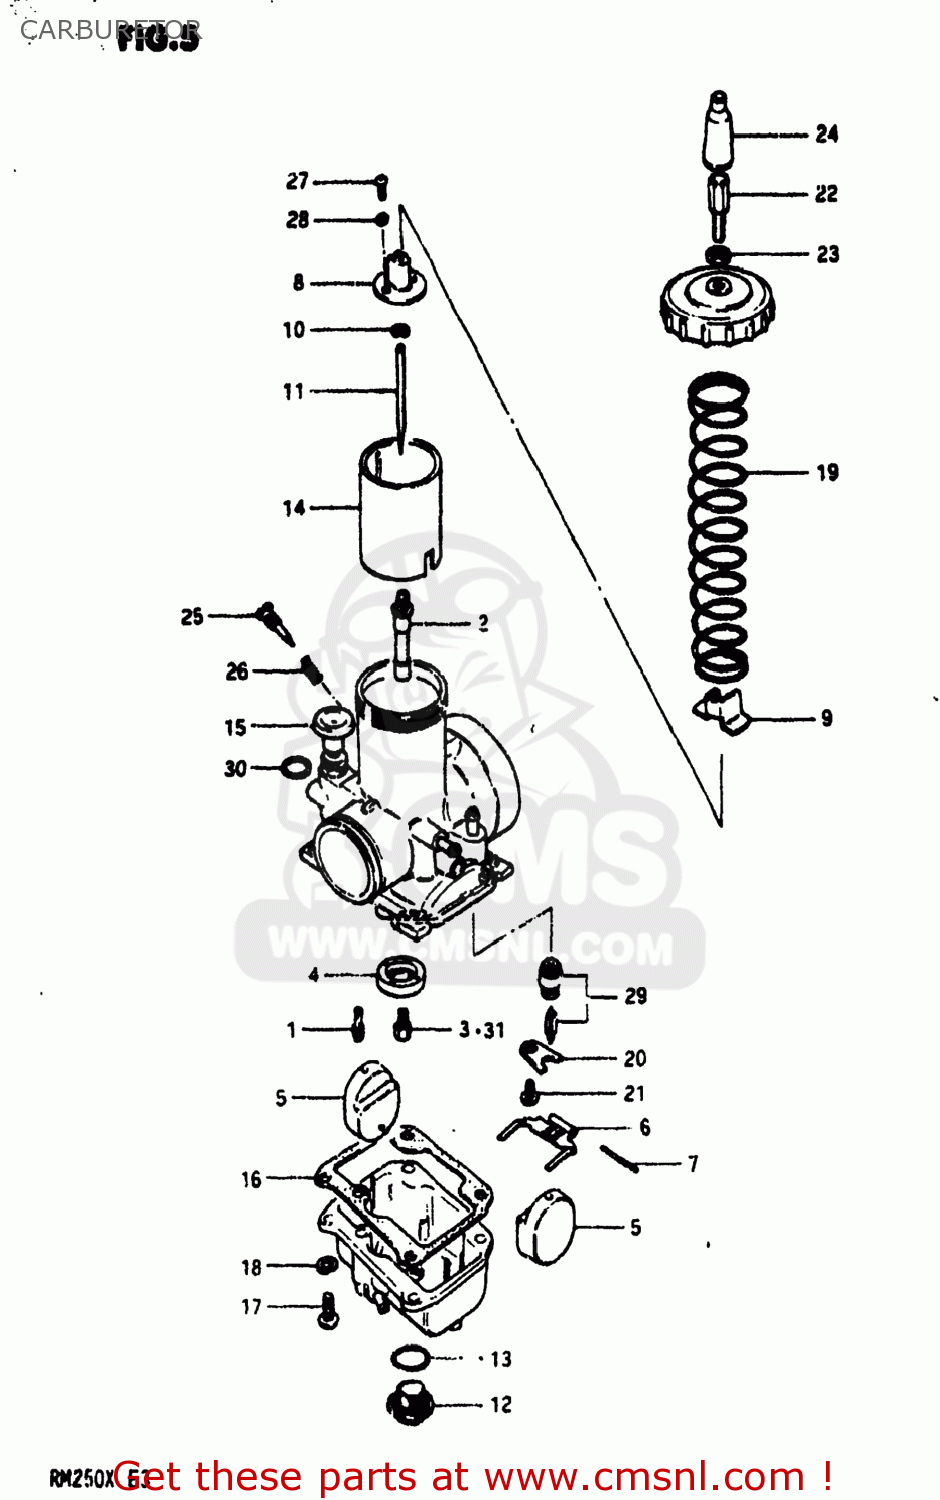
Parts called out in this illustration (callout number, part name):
1	JET,PILOT
2	JET,NEEDLE
3	JET
4	RING,MAIN JET FIXING
5	FLOAT
6	ARM,FLOAT
7	PIN,FLOAT
8	CONNECTOR
9	COVER,HOLDER
10	CLIP
11	NEEDLE JET
12	PLUG
13	O RING(D:1.5,ID:19.5)
14	VALVE,THROTTLE
15	VALVE ASSEMBLY,STARTER
16	GASKET,FLOAT CAHMBER (NAS)
17	SCREW
18	LOCK WASHER
19	SPRING
20	PLATE
21	SCREW 4X6
22	ADJUSTER,CABLE
23	NUT
24	CAP,CABLE ADJUSTER
25	SCREW,PILOT AIR
26	SPRING
27	SCREW
28	LOCK WASHER
29	VALVE ASSEMBLY,NEEDLE
30	O-RING
31	JET
